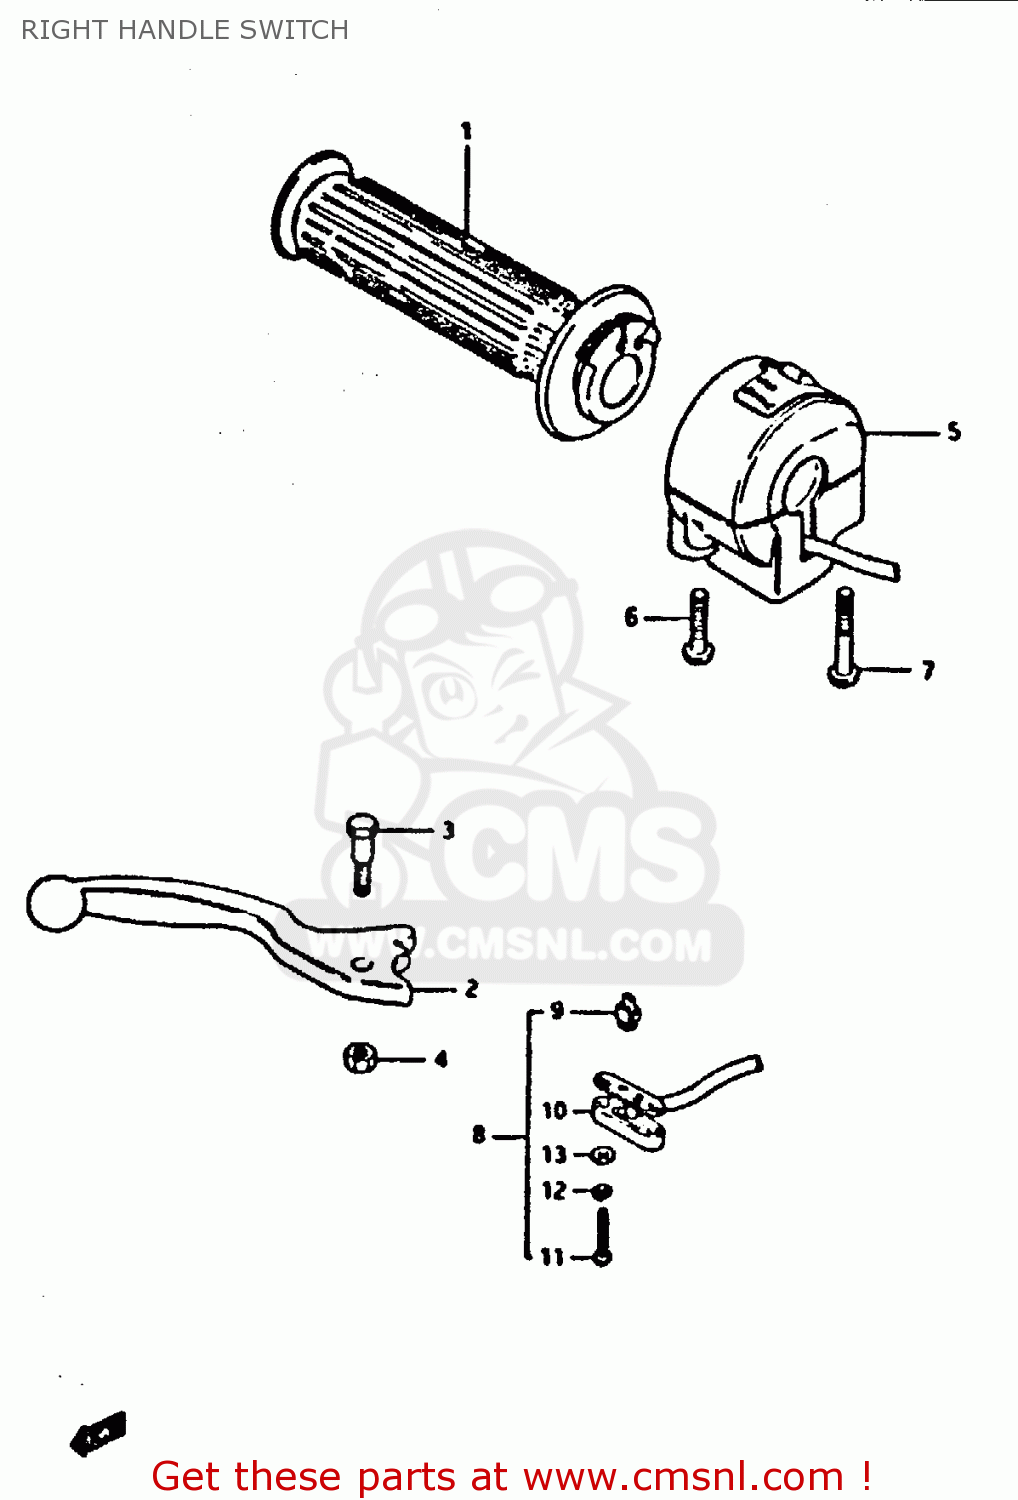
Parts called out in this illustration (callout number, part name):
1	GRIP,THROTTLE
2	LEVER,BRAKE
3	BOLT
4	NUT 6MM
5	SWITCH ASSY, HANDLE RH
6	SCREW
7	SCREW
8	SWITCH ASSEMBLY
9	CONTACT,SWITCH
10	COVER,FR BK TERMINAL BASE
11	SCREW
12	LOCK WASHER
13	WASHER
